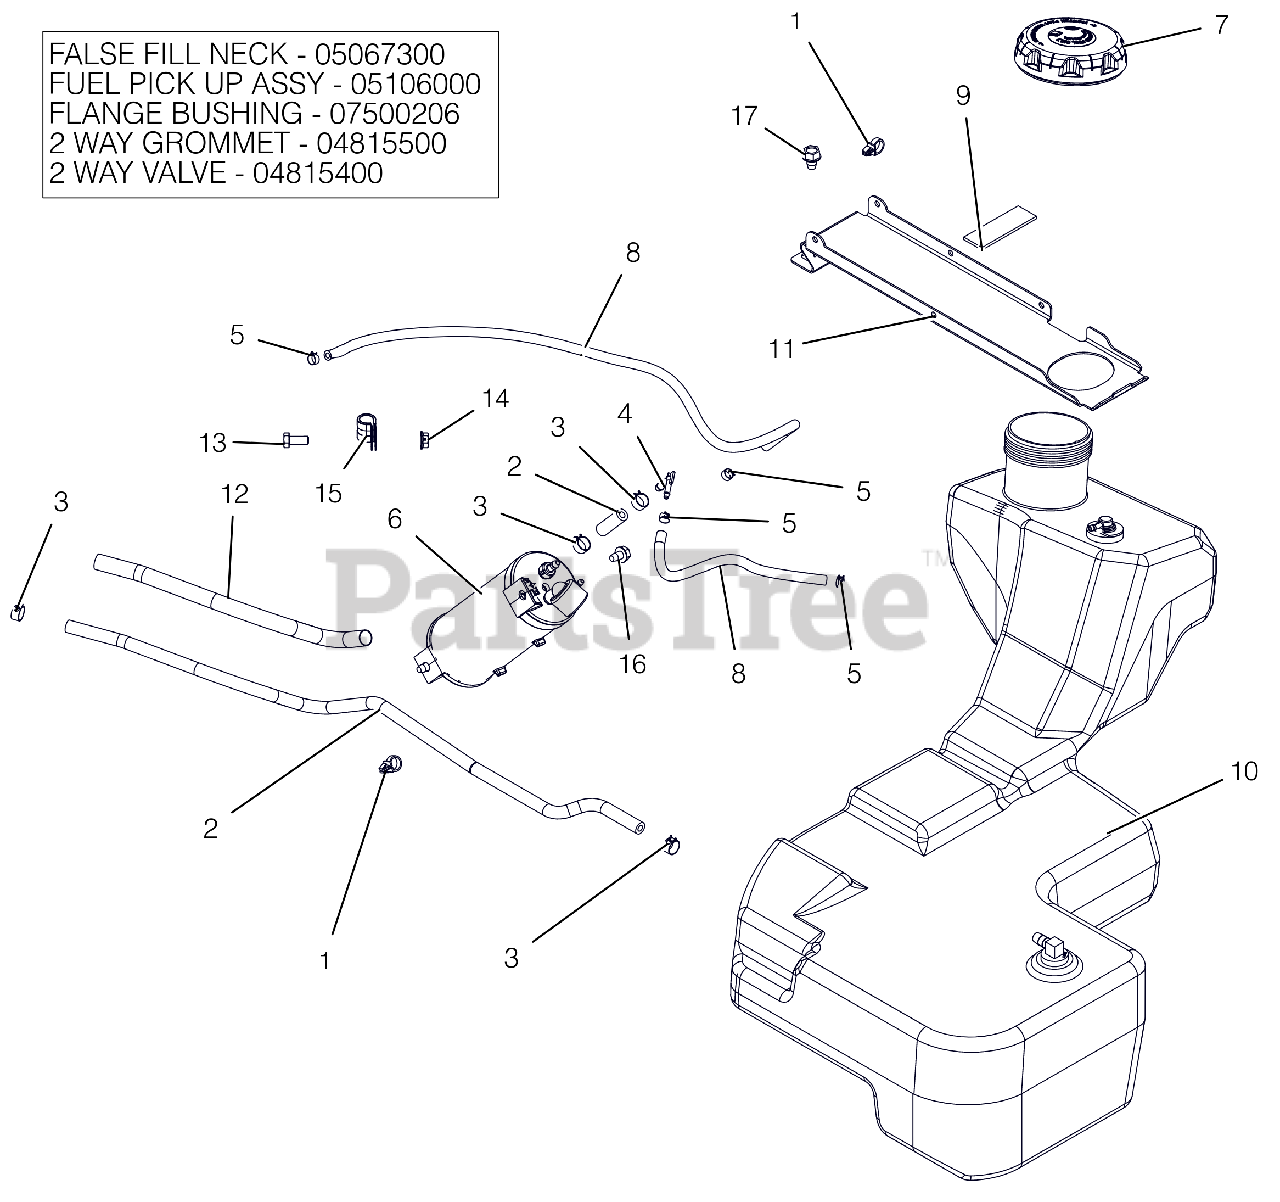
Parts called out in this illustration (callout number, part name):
1	ROUTING CLIP (1/2" ID)
2	HOSE, .25 LOW-PERM BULK GAS
3	CLAMP, FUEL LINE
4	FITTING-3/16X1/4 90DEGREE VAC
5	CLAMP-HOSE, SPRING .188
6	CANISTER, 400 CC CARB
7	CAP, FUEL VENTIN AUTOLOCK
8	HOSE, .188 30R7 BULK
9	PAD,RBR 1.0"X3.0" W/ADHESIVE
10	ASM, HD FUEL TANK
10	INSERT, FUEL NECK FALSE FILL
10	ASM, HD FUEL PICK-UP
10	BSHG-FLG .375X1.062X.625 NITR
10	GROMMET, 2-WAY
10	VALVE, 2-WAY
11	BRKT, FUEL TANK HOLD DOWN
12	SLEEVE, THERMAL 12"
13	@BLT-HEX .31-18X.75 GR5 YWZC
14	@NUT-LK-CTR-FLG .31-18 YZ GR F
15	CLAMP, CUSHIONED STEEL
16	@SCR-TAP .31-18X.50 HWH TR YWZ
17	@SCR-TAP .38-16X.50 HWH TR YWZ
